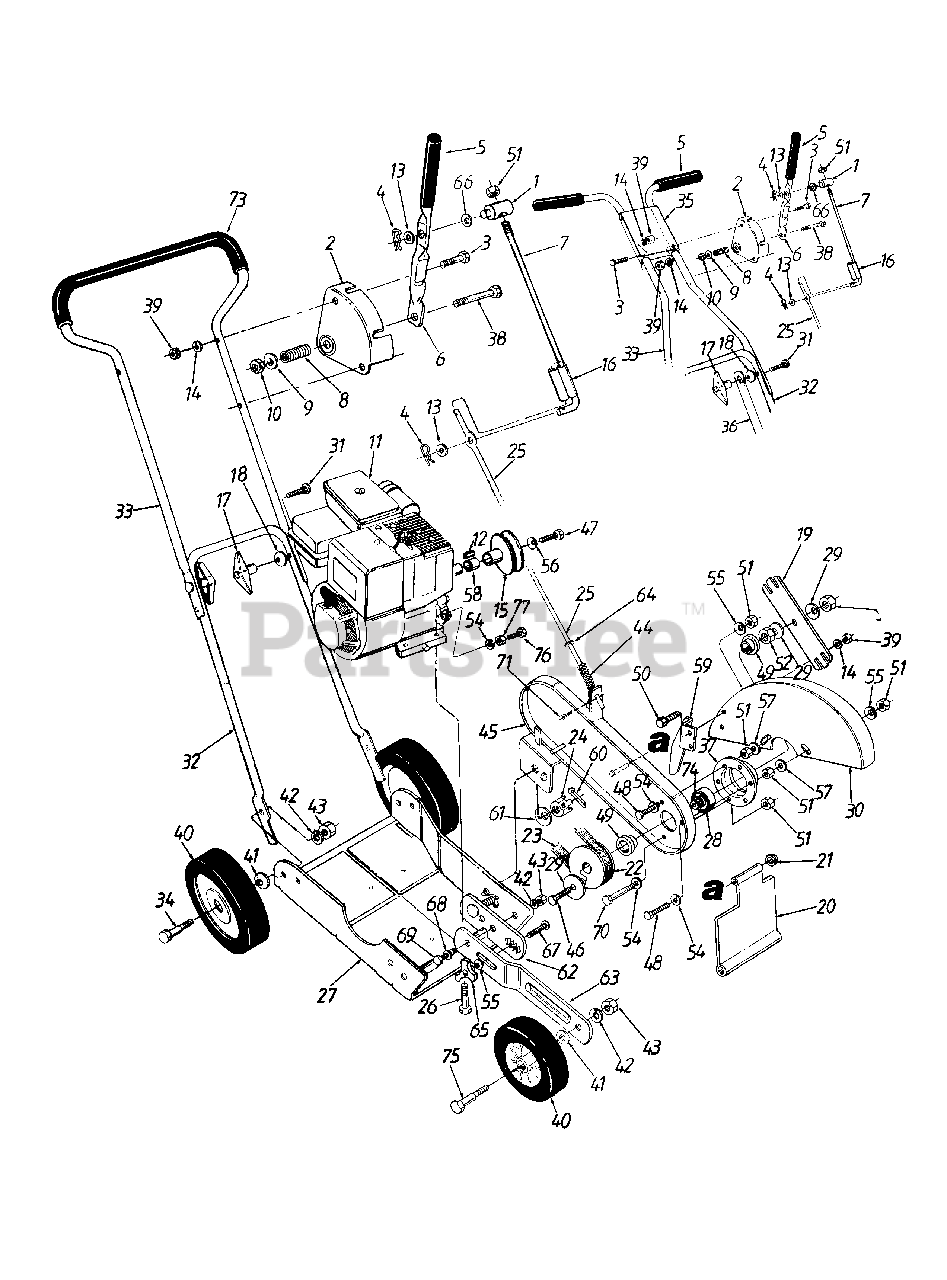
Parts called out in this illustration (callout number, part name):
1	Ferrule
4	Hairpin Clip
5	Foam Grip
7	Upper Clutch Rod
8	Compression Spring 1.38" Lg.
9	Fl-Wash. .344" I.D.
10	Hex L-Nut 5/16-18 Thd.
11	Engine
12	Sq. Key 3/16" x 1" Lg.
13	Fl-Wash. .344" I.D.
14	L-Wash. 1/4" I.D.
15	Engine Pulley
16	Clutch Rod Lock
17	Wing Nut Ass'y.
18	Saddle Wash. .32" I.D. x .937" OD.
20	Edger Guide Flap
21	Push Cap
22	3/8" "V"-Pulley
23	"V"-Belt
24	Hex Slotted Nut 1/2-20 Thd.
25	Lower Clutch Rod
26	Hex L-Wash. TT-Tap Scr. 3/8-16 x 1" Lg.
29	Bell-Wash. 5/8" I.D. x 1-1/4" O.D.
34	Shld. Bolt 3/8-16 Thd.
38	Hex Bolt 5/16-18 x 2" Lg.
39	Hex Nut 1/4-20 Thd.
40	Wheel Ass'y.
41	Bell-Wash. .38" I.D. x .88" O.D.
42	L-Wash. 3/8" I.D.
43	Hex Nut 3/8-16 Thd.
44	Comp. Spring 2" Lg.
47	Hex Bolt 3/8-24 x 1.5" Lg. (Gr. 5)
48	Hex Cap Bolt 5/16-18 x 1-1/4" Lg.
49	Shld. Spacer .626" I.D.
50	Hex Bolt 1/4-20 x .5" Lg.
51	Hex Nut 5/16-18 Thd.
52	Hex Jam Nut 5/8-18 Thd.
53	Hex Ins. L-Nut 5/8-18 Thd.
54	L-Wash. 5/16" I.D.
55	Bell-Wash. .345" I.D. x .88" O.D.
56	Bell-Wash. .396" I.d. x 1.14" O.D.
57	Fl-Wash. .312" I.D. x .75" O.D.
58	Spacer .748" I.d. x .985" O.D.
61	Bell-Wash. .515" I.D. x 1.14" O.D.
65	Hand Knob
66	Spring Wash. .32" I.D.
67	Carr. Bolt 5/16-18 x 1" Lg. (Special)
68	Spacer .383" I.D. x .508" O.D.
69	Hex Bolt 3/8-16 x 1" Lg.
70	Shld. Bolt 5/16-18 x 1.27" Lg.
71	Cotter Pin 1/8" Dia. x 1" Lg.
73	Foam Grip
74	Fl-Wash. .64" I.D. x 1.12 O.D.
75	Shld. Bolt .498" Dia. x 1.64" Lg.
76	Hex Bolt 5/16-24 x 2.75" Lg. (Gr. 5)
77	Hex Nut 5/16-24 Thd.
